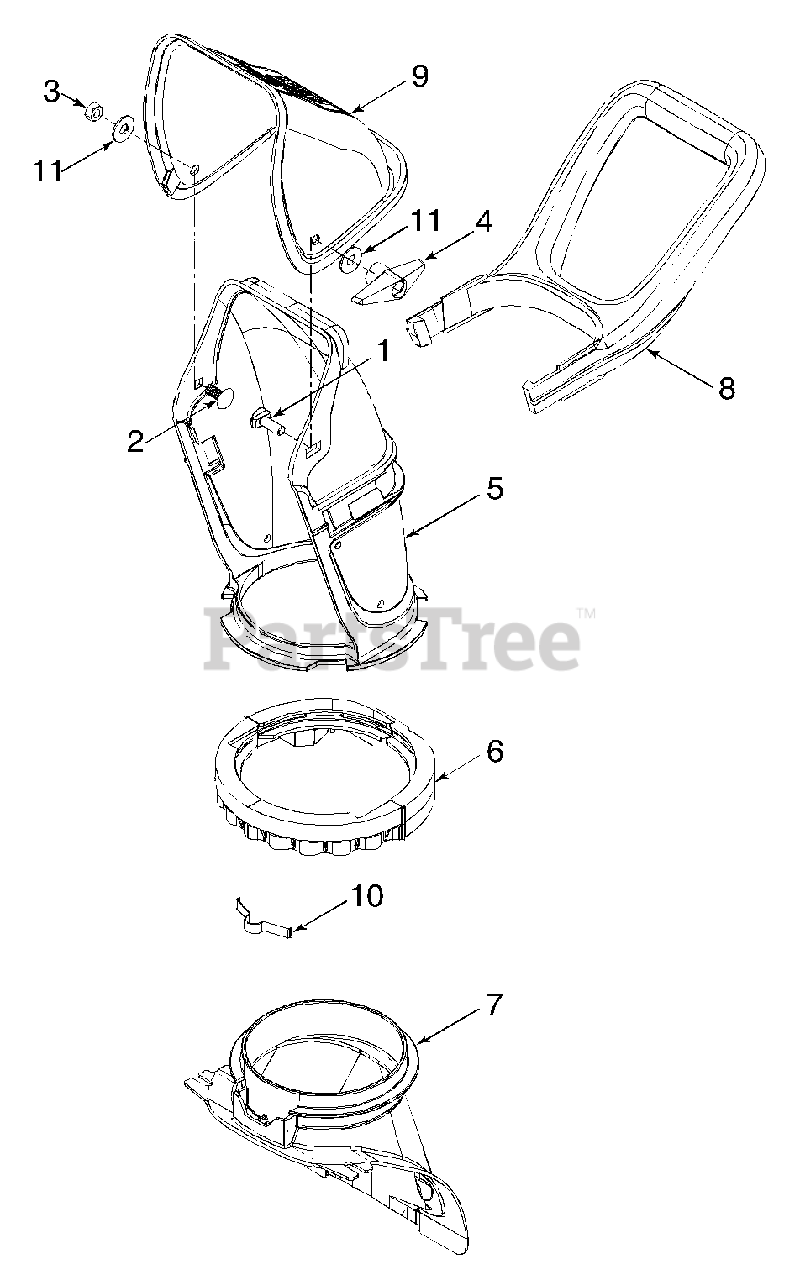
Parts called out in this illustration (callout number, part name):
1	Carriage Screw, 5/16-18 x 1.0
2	Carriage Bolt, 5/16-18 x.075 GR 1
3	Hex Flange Lock Nut, 5/16-18, Gr. 5
4	Handle Knob Assembly 5/16-18
5	Lower Chute 5" Dia
6	Ring-Lower Chute
7	Chute, Adapter 5" Dia
8	Handle-Chute 5" Dia
9	Upper Chute
10	Chute Adjustment Spring
11	Flat Washer,.349 ID x .879 OD x .063
